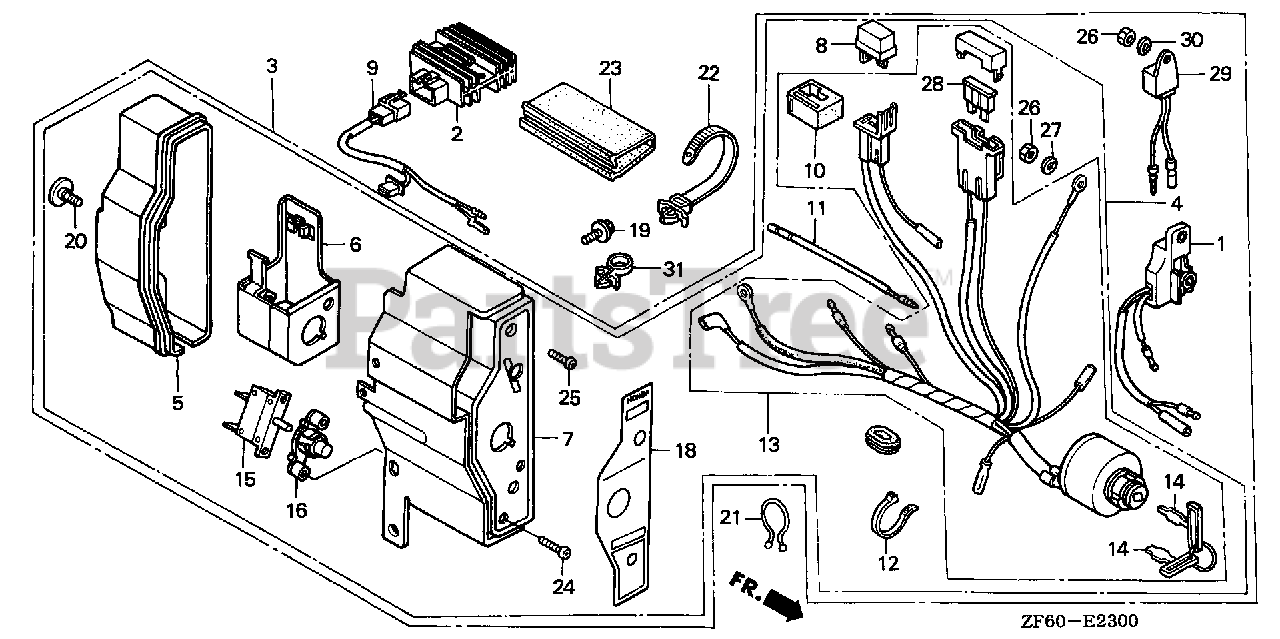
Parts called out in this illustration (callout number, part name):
1	ALERT UNIT, OIL (SEL) (NOT AVAILABLE)
3	BOX ASSY., CONTROL (3A) *R8* (ALERT) (BRIGHT RED) (NOT AVAILABLE)
4	BOX ASSY., CONTROL (3A) *R280* (EXP-ALERT) (POWER RED)
5	CASE, CONTROL
6	BRACKET, CASE MOUNTING
7	PANEL, CONTROL *R8* (BRIGHT RED)
7	PANEL, CONTROL *R280* (POWER RED)
8	RECTIFIER ASSY., SILICON (SHINDENGEN)
10	SUSPENSION, CONNECTOR
13	SWITCH ASSY., COMBINATION (3A-CHARGE)
14	KEY (HONDALOCK)
15	PROTECTOR, CIRCUIT (3.5A)
16	LENS ASSY., PROTECTOR
18	MARK, CONTROL BOX (EXP)
18	PANEL, CONTROL BOX (EXTERNAL-ALERT) (NOT AVAILABLE)
19	BOLT, FLANGE (6X12) (CT200)
20	SCREW, SPECIAL (6X12)
21	CLIP, PURSE LOCK
22	STRAP, CABLE (118MM) (BLACK)
23	TUBE, FASTENER (30MM)
24	SCREW, PAN (3X12)
25	SCREW, PAN (4X12)
26	NUT, HEX. (4MM)
27	WASHER, SPRING (4MM)
28	FUSE, BLADE (15A)
31	HOLDER, STOP SWITCH WIRE
